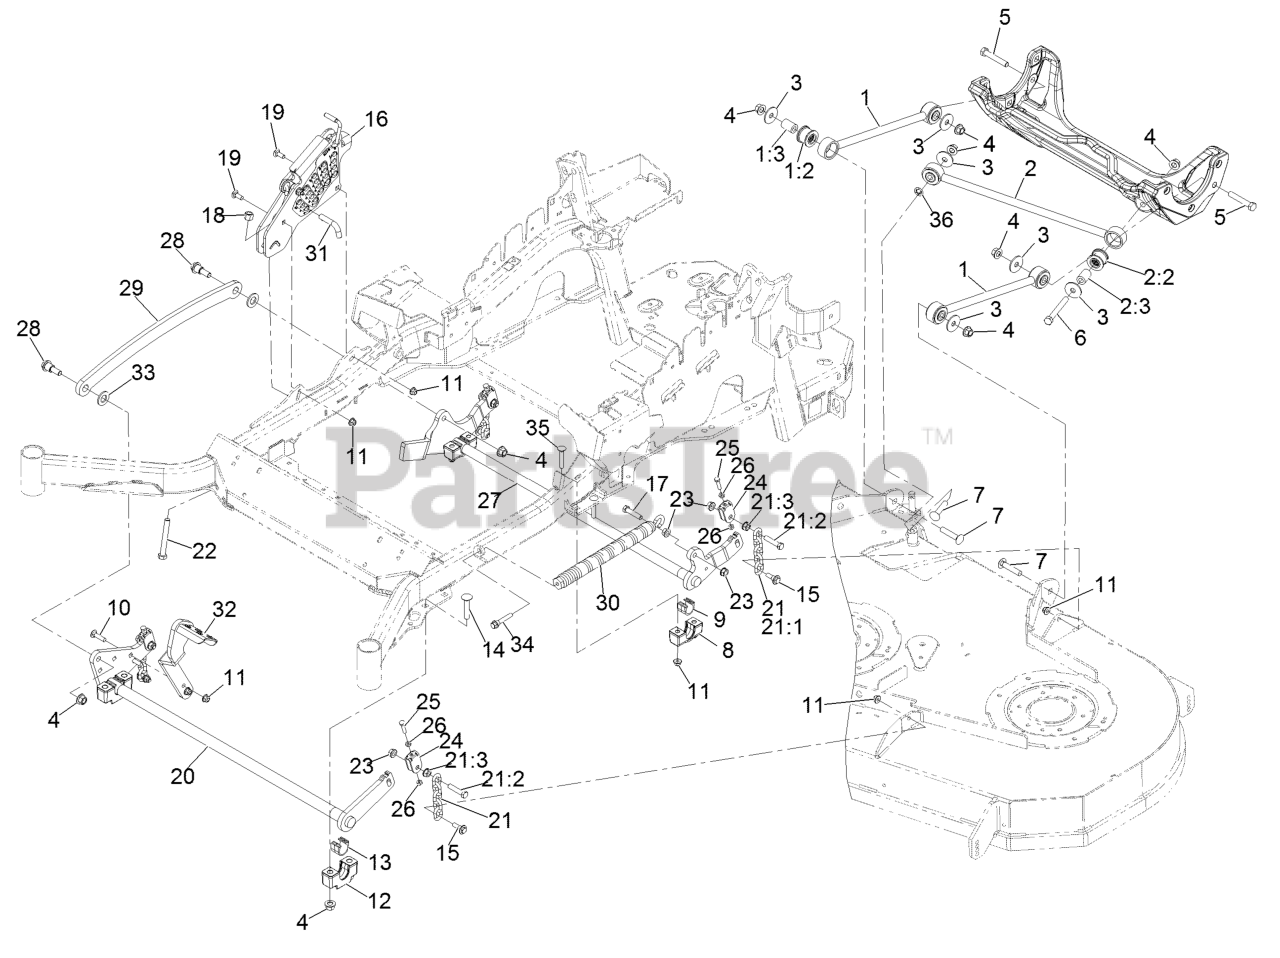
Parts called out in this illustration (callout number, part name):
1	DECK STRUT ASM
1:2	BUSHING-SUSPENSION, RUBBER
2	PANHARD ROD ASM
2:2	BUSHING-SUSPENSION, RUBBER
3	WASHER-THRUST
4	Nut-Lock 1/2-13
5	SCREW-HH
6	SCREW-HH
7	SCREW-CARR
8	SUPPORT-CROSS SHAFT, BEARING REAR
9	BEARING-CROSS SHAFT, REAR
10	SCREW-CARR
11	NUT-HF, NI
12	SUPPORT-CROSS SHAFT, BEARING
13	BEARING-CROSS SHAFT, FRON
14	Bolt-Carriage 1/2-13 X 2 1/2 Spl Neck
15	SCREW-SHOULDER, HHF
16	HOC ASM
17	SCREW-HH
18	NUT-LOCK, NI
19	BOLT-CARR
20	DECKLIFT-FRONT
21	DECK LIFT CHAIN ASM
21:1	CHAIN-LIFT, DECK
21:2	SCREW-HH
22	BOLT-TAP
24	YOKE-ADJUST, DECK
25	SCREW-HH
26	NUT-JAM
27	LIFT-DECK, REAR
28	SCREW-SHOULDER, HHF 1/2-13 X 1.12
29	LINK-LIFT, DECK
30	SPRING-EXTENSION
31	PIN-HOC
32	LEVER-FOOT
33	WASHER-FLAT
34	BOLT-SHOULDER
35	Bolt-Carriage 3/8-16 X 2 1/4
36	NUT-PUSH
